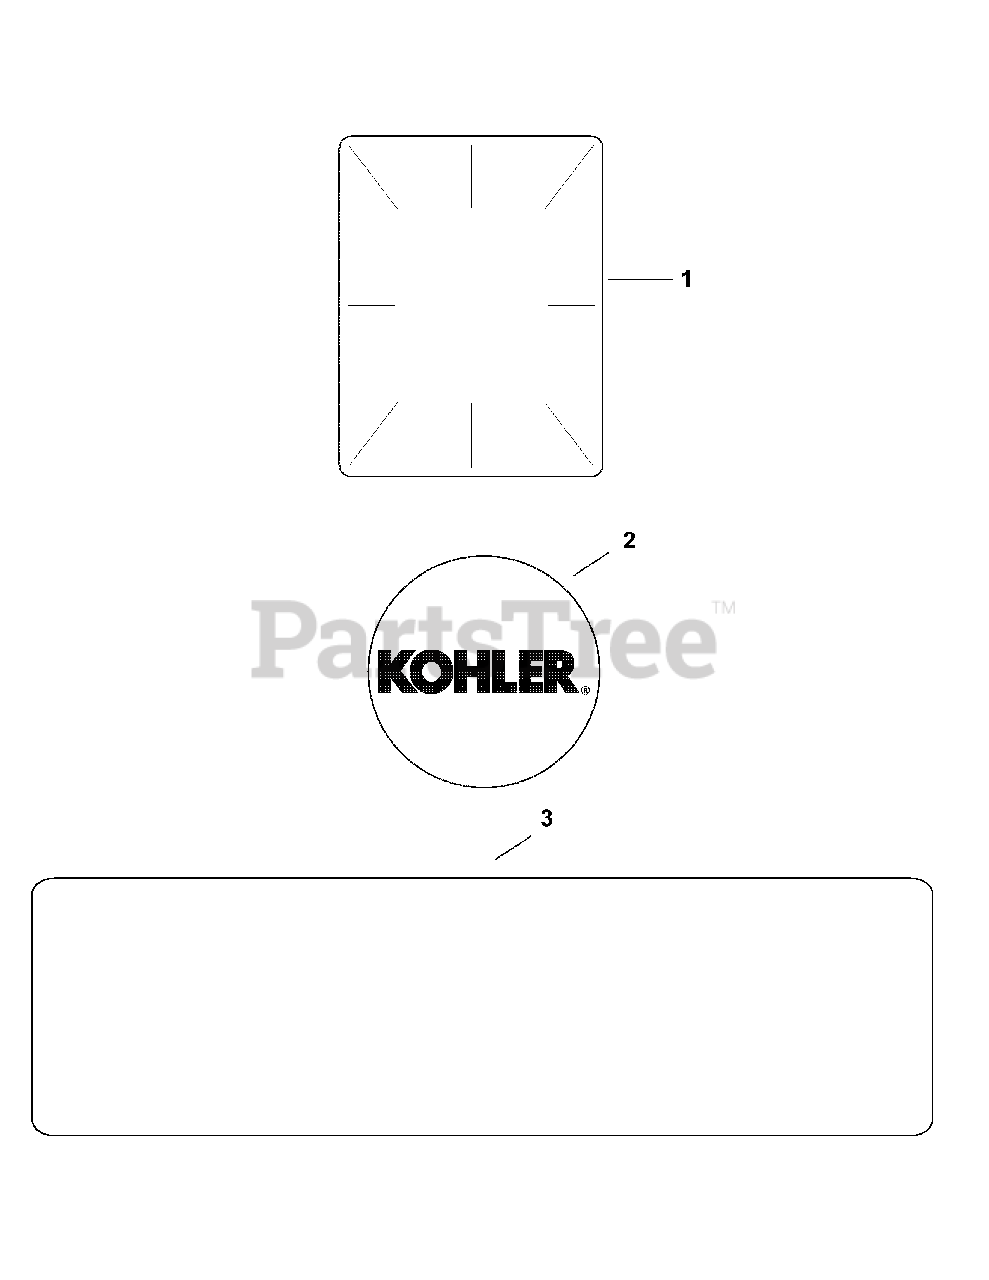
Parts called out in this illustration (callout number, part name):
1	Decal, Clear Laminate
2	Decal, Grass Screen
3	Decal, 20HP
